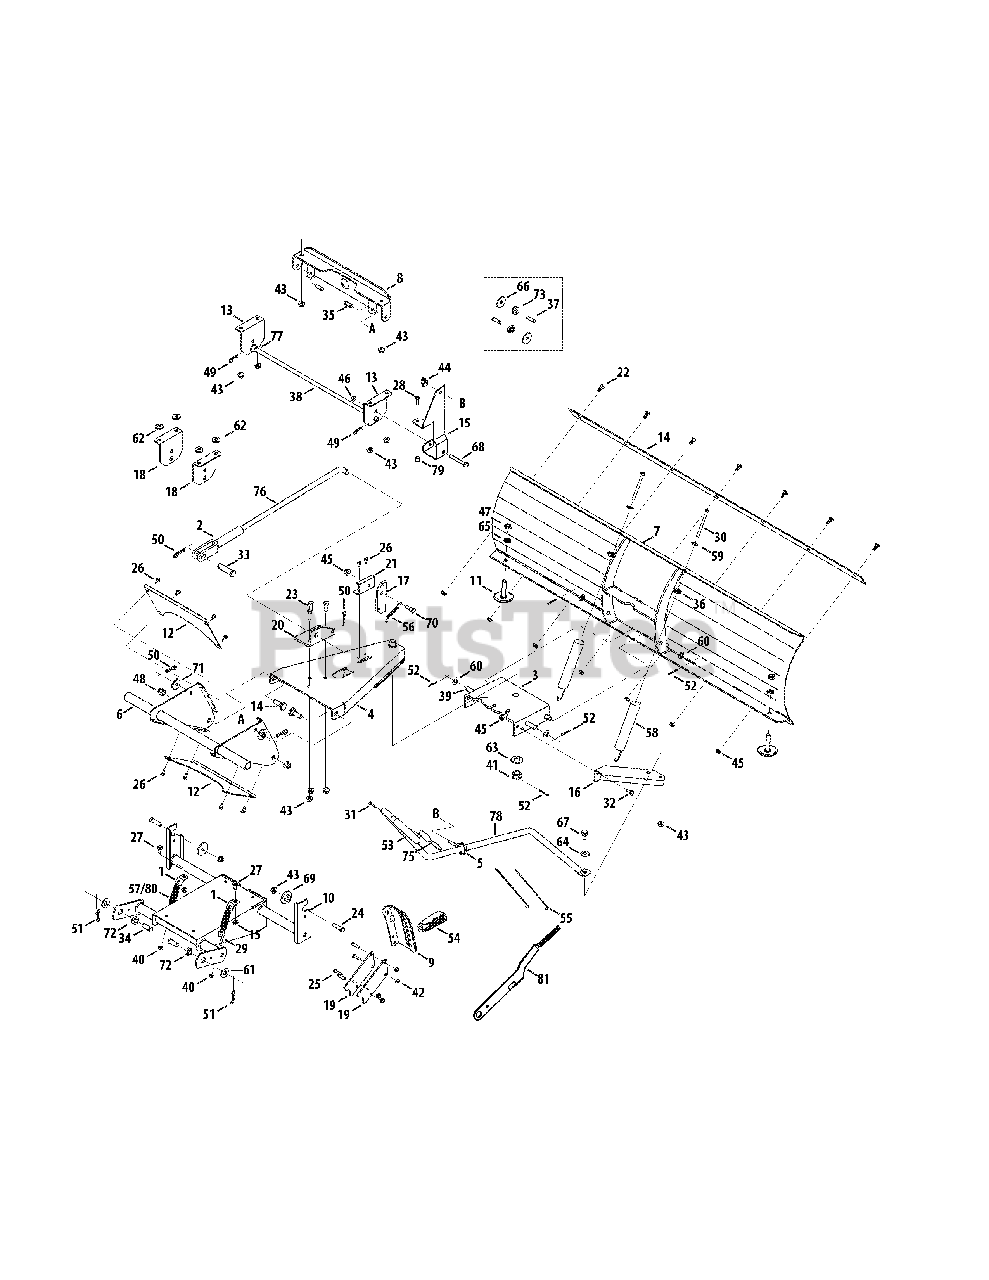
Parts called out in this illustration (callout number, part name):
1	Spring Mount Bracket
2	Clevis Adjustment Assembly
3	Blade Pivot Assembly
4	Blade Frame Assembly
5	Eyebolt Assembly
6	Bracket Assembly
7	52" Blade Assembly
8	Blade Mount Bracket Assembly
9	Blade Height Adj. Index Bracket
10	Lift Bracket Assembly
12	Cover Brace
13	Mounting Bracket
14	52" Blade Scraper Plate
15	Handle Mount Bracket
16	RH Blade Adjustment Arm
17	Blade Lock Plate
18	Mount Bracket
19	Lift Arm Stiffener Bracket
20	Front Lift Bracket
21	Pivot Bracket
22	Carriage Bolt, 5/16-18 x .750
23	Hex Screw, 3/8-16 x 1.00
24	Hex Screw, 3/8-16 x 1.50
25	Hex Screw, 1/4-20 x 1.00
26	Hex Washer Screw, 1/4-20 x .50
27	Hex Washer Screw, 5/16-18 x .875
28	Hex Washer Screw, 1/4-20 x 1.000
29	Eye Bolt, 1/4-20
30	Hex Screw, 5/16-18 x 3.50
31	Machine Screw, #10-24 x 1.375
32	Hex Screw, 5/16-18 x .75
33	Clevis Pin, .625 x 2.40
34	Clevis Pin, .500 x 1.25
35	Clevis Pin, .375 x .969
36	Spring Insert
37	Clevis Pin, 3/8 x 1.123
38	Rod, .50 x 22.65
39	Rod, .50 x 10.428
40	Nut, 1/4-20
41	Slotted Nut, 3/4-16
42	Flange Lock Nut, 1/4-20
43	Flange Lock Nut, 3/8-16
44	Wing Nut, 5/16-18
45	Flange Lock Nut, 5/16-18
46	Jam Lock Nut, 3/8-16
47	Jam Nut, 1/2-13
48	Hex Lock Nut, 1/2-13
49	Click Pin, .092 x 1.64
50	Cotter Pin, .125 x 1.75
51	Bow-Tie Cotter Pin
52	Cotter Pin, 1/8 x 1.25
53	Foam Grip
54	Grip, .50
55	Cable Tie, 3/16 x 7.4
56	Extension Spring, .38 x 3.25
57	Extension Spring, .99 x 3.50
58	Extension Spring, 1.25 x 6.7
59	Flat Washer, .349 x .879 x .063
60	Flat Washer, .530 x .930 x .050
61	Flat Washer, .531 x 1.250 x .100
62	Flat Washer, .385 x 1.000 x .135
63	Flat Washer, .760 x 1.500 x .120
64	Flat Washer, .570 x 1.120 x .062
65	Lock Washer, 1/2
66	Flat Washer, .406 x 1.500 x .105
67	Shoulder Bolt, 3/8-16 x .496 x .336
68	Shoulder Bolt, 3/8-16 x .500 x 2.38
69	Shoulder Spacer, .8840 x .190
70	Shoulder Screw, 5/16-18 x .405 x .435
71	Shoulder Spacer, 1.375 x .380 x .183
72	Shoulder Spacer, .50 x .75 x .170
73	Shoulder Spacer, .375 x .75 x .170
74	Shoulder Screw, 1/2-13 x .625 x .36
75	Blade Release Cable
76	Lift Rod
77	Flange Bearing, .503 x .75
78	Blade Adjust Handle
79	Spacer, .258 x .50 x .50
80	Extension Spring, 1.4 x 3.5 x .200
81	Lift Handle
